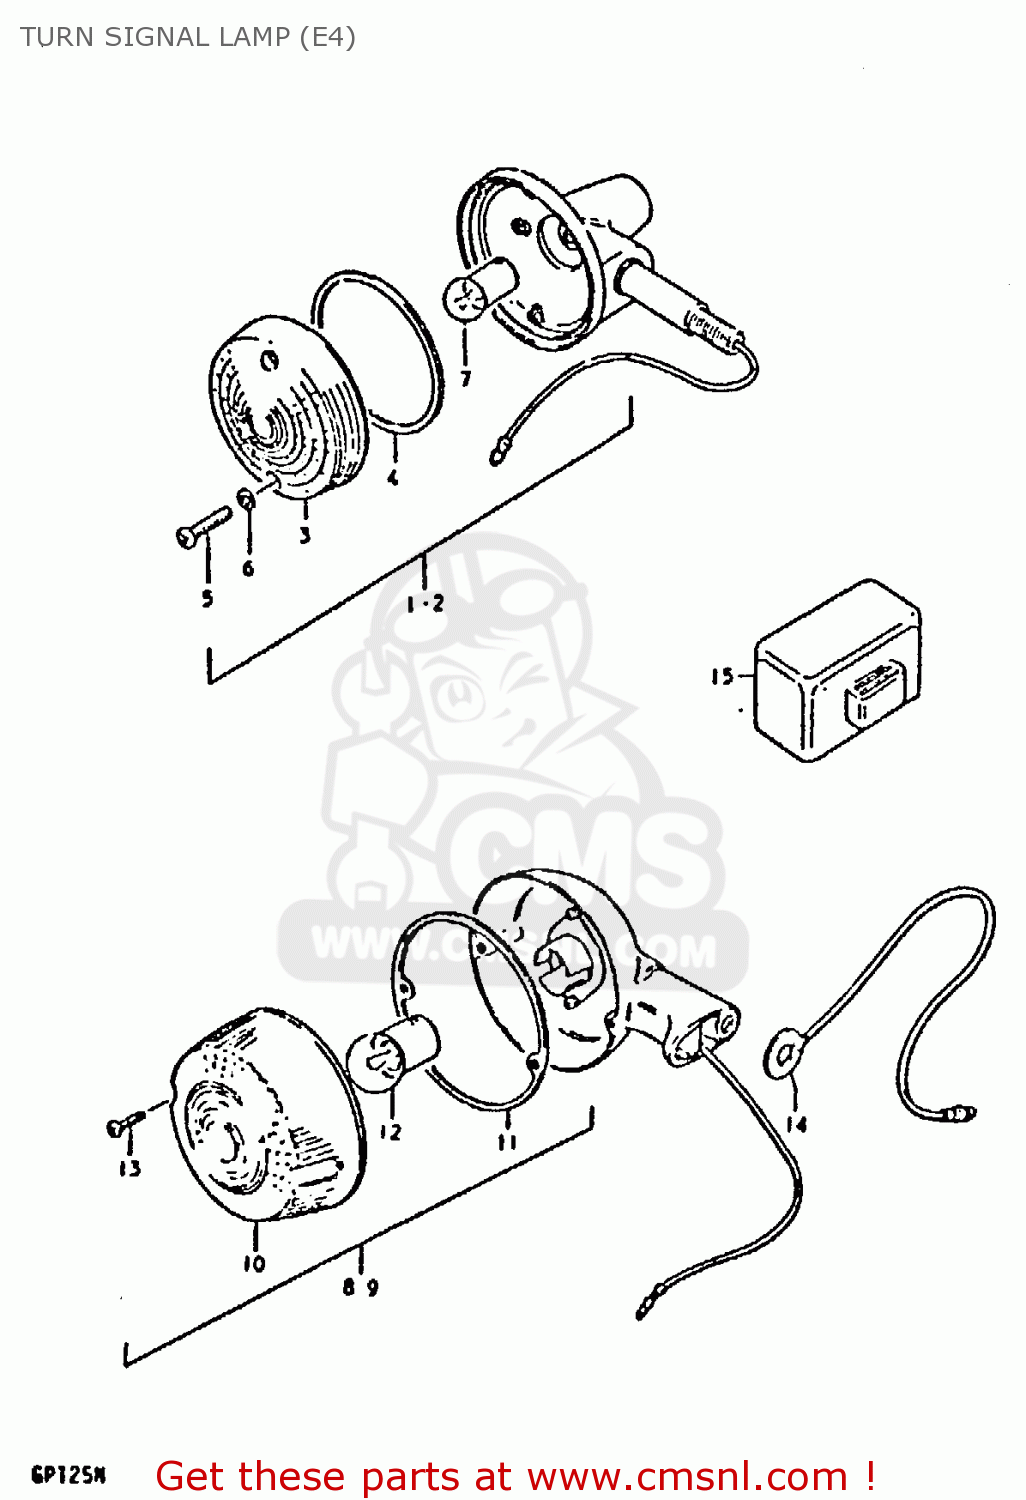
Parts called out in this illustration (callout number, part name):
1	LAMP ASSY, FRONT TURN SIGNAL
2	LAMP, REAR TURN SIGNAL
3	LENS
4	GASKET (NAS)
5	SCREW
6	GASKET (NAS)
7	BULB (6V,10W)
15	RELAY ASSY, TURN SIGNAL
